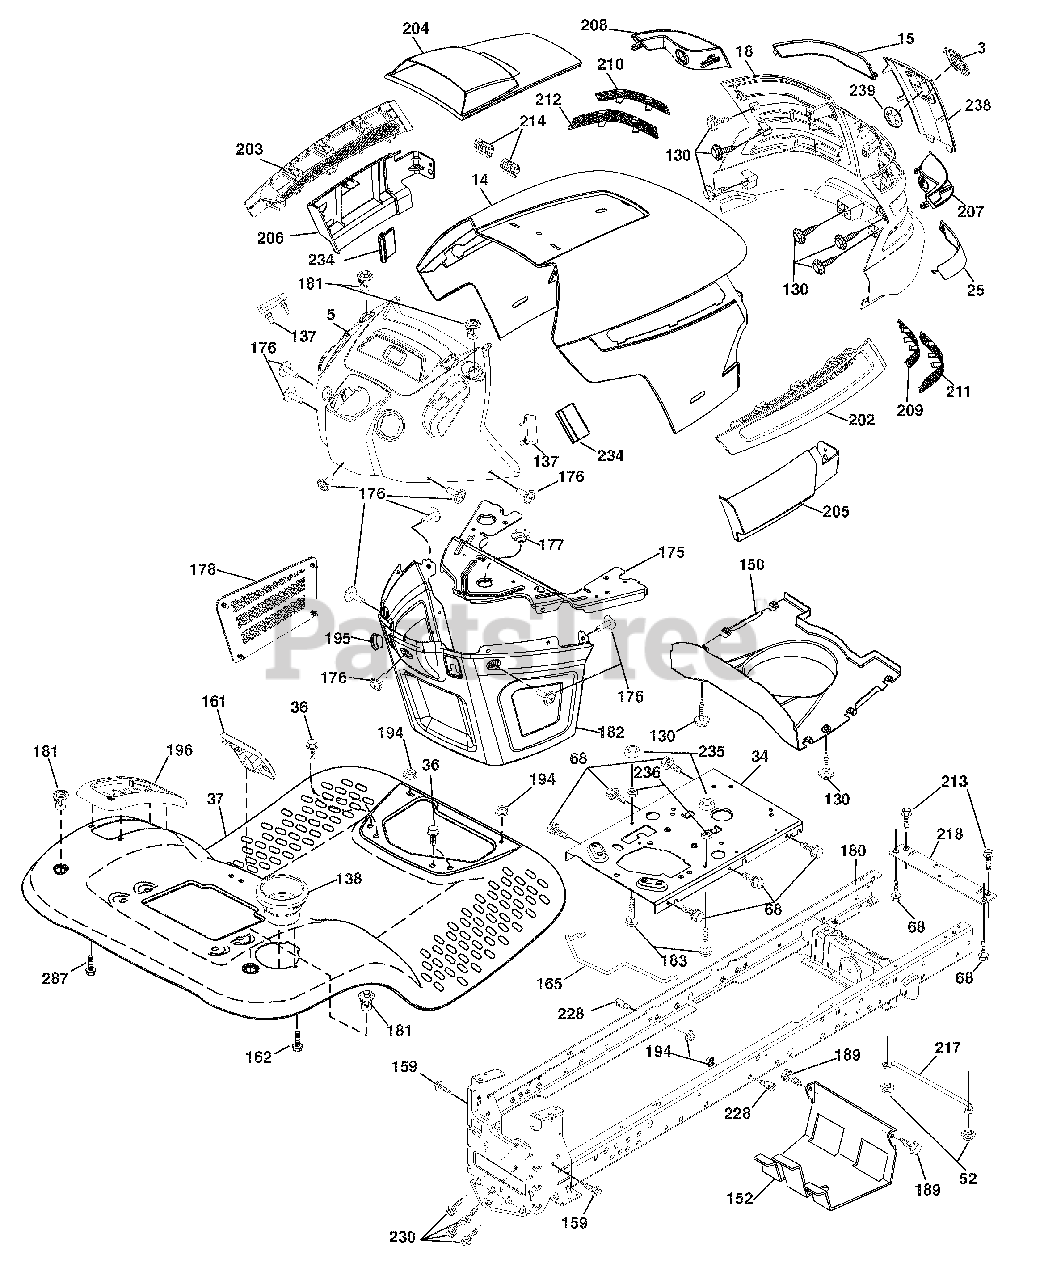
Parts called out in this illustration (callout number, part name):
3	Logo
14	Hood
18	Grille Asm.
34	Plate Engine
36	Screw 5/16-18 x 3/4
52	Nut Lock 5/16-18
68	Screw 5/16-18 x 1/2
130	Screw #10 x 0.750 BOS Thread
137	Bumper Dash
138	Cupholder
152	Shield Browning
161	Window Fuel
165	Support Tank Rear
175	Crossmember
176	Screw 10-24 x 5/8
177	Bushing Steering
178	Cargo Net Asm.
180	Chassis
181	Bushing Mtg. Fender Crgo
182	Dash Lower
183	Bolt Fin Hex 5/16-18 unc x 1-1/4
189	Screw 5/16-18 x 3/4
194	Nut Lock Hex Flange 5/16-18
195	Plug Hole Dash Lower
196	Console Asm. Deck Lift
202	Vent Side Hood RH
203	Vent Side Hood LH
204	Vent Top Hood
205	Skirt Hood Side RH
206	Skirt Hood Side LH
209	Insert Hex Top RH
210	Insert Hex Top LH
211	Insert Hex Bottom RH
212	Insert Hex Bottom LH
213	Bolt 5/16-18 unc x 3/4
214	Clip Retainer Tinner
218	X-Piece Hood Stop
228	Stud Fastner
233	Bolt Shoulder
234	Bumper Hood
235	Spacer Fender
236	Nut Lock 5/16-18 unc
287	Screw Hex Washead 1/4-20 x 3/8
